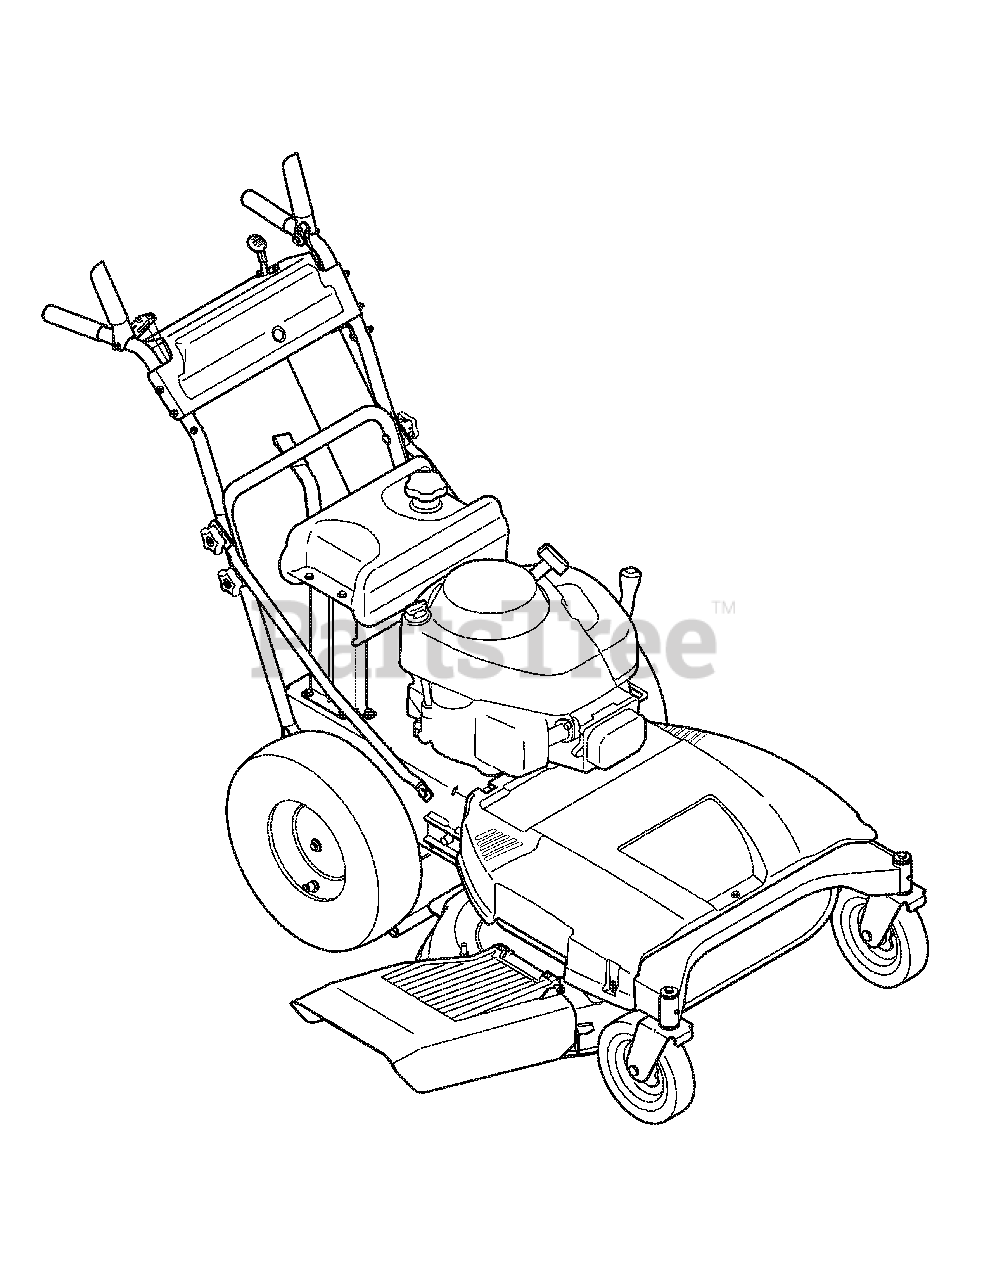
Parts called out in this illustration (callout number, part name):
NA	Blade Adapter
NA	Ignition Key
NA	Grass Bag
